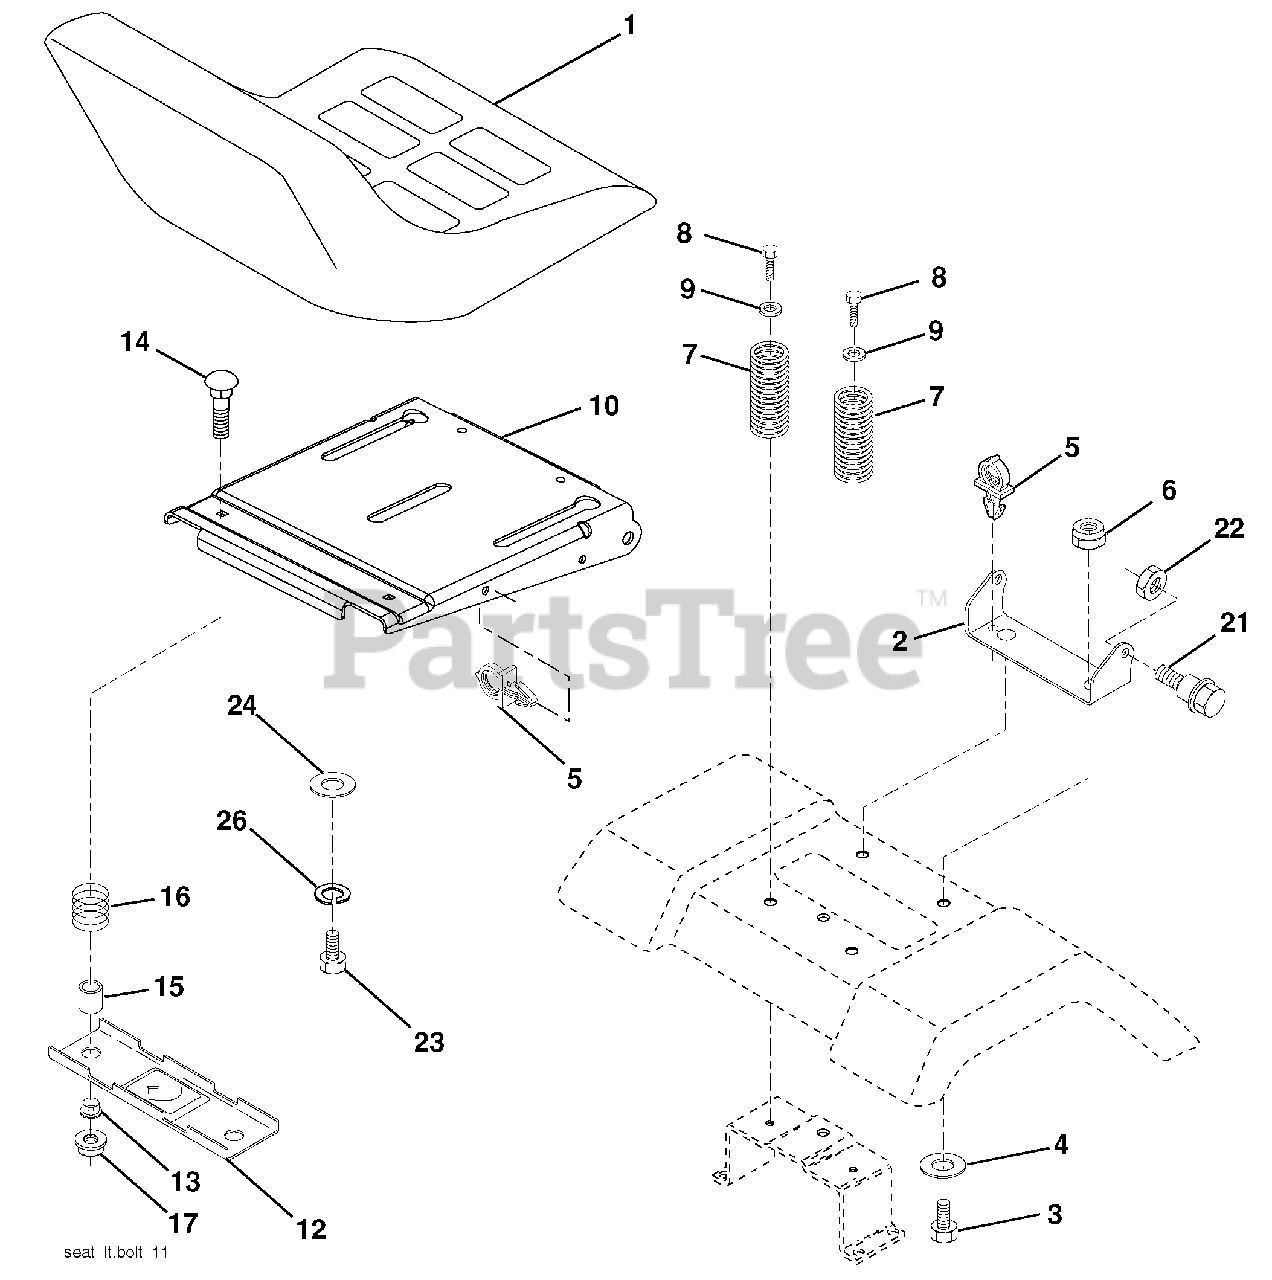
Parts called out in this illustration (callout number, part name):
2	Bracket Seat Pivot
3	Bolt Hex 3/8 - 16 x 1
4	Washer 13/32 x 1 x10 Ga.
5	Clip Push-In Hinged
6	Nut Lock Hex w/Ins 3/8 - 16
7	Spring Seat Cprsn 2 250 Blk Zi
8	Screw 3/8-16 x 1.5
9	Washer 13/32 x 1 x 14 Ga.
10	Pan Asm. Seat
12	Bracket Pnt Mounting Switch
13	Bushing Snap Blk Nyl
14	Bolt Rdhd Sht Nk 1/4 - 20 x 1 -1/2
15	Spacer Split .28 x .96
16	Spring Cprsn
17	Nut Lock 1/4 Lge Flg
21	Bolt Shoul der 5/16-18 unc-2A
22	Nut Lock Hex w/Ins 5/16 - 18
23	Bolt Hex
24	Washer 17/32 x 1-3/16 x 12 Ga.
26	Washer Lock Hvy Hlcl Spr 1/2
